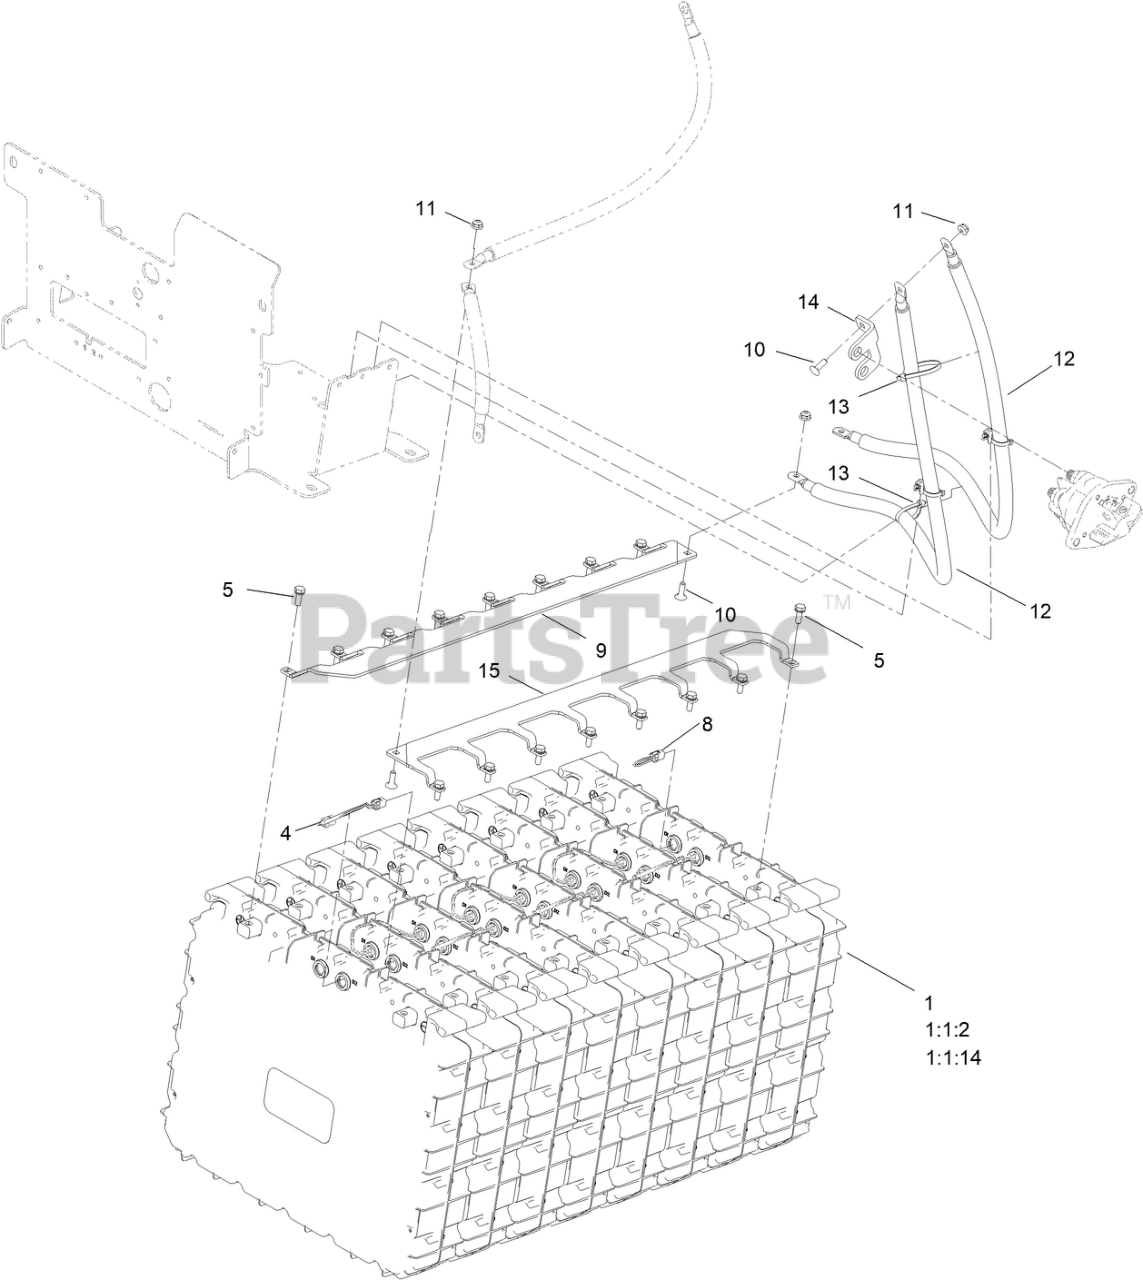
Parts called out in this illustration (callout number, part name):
1	BATTERY ASM
1:1:2	DECAL-WARNING, BATTERY
1:1:14	NUT-MOUNTING, JWPF PANEL LOCK
4	HARNESS-WIRE, DATA INTERFACE
5	SCREW-SEMS
8	HARNESS-WIRE, CAN TERMINATOR
9	BUSBAR-8, RD
10	BOLT-CARR
11	NUT-HF
12	CABLE-BATTERY,RD ASM
13	TIE-CABLE
14	BUSBAR-2, SWITCH
15	BUSBAR-8, BK
